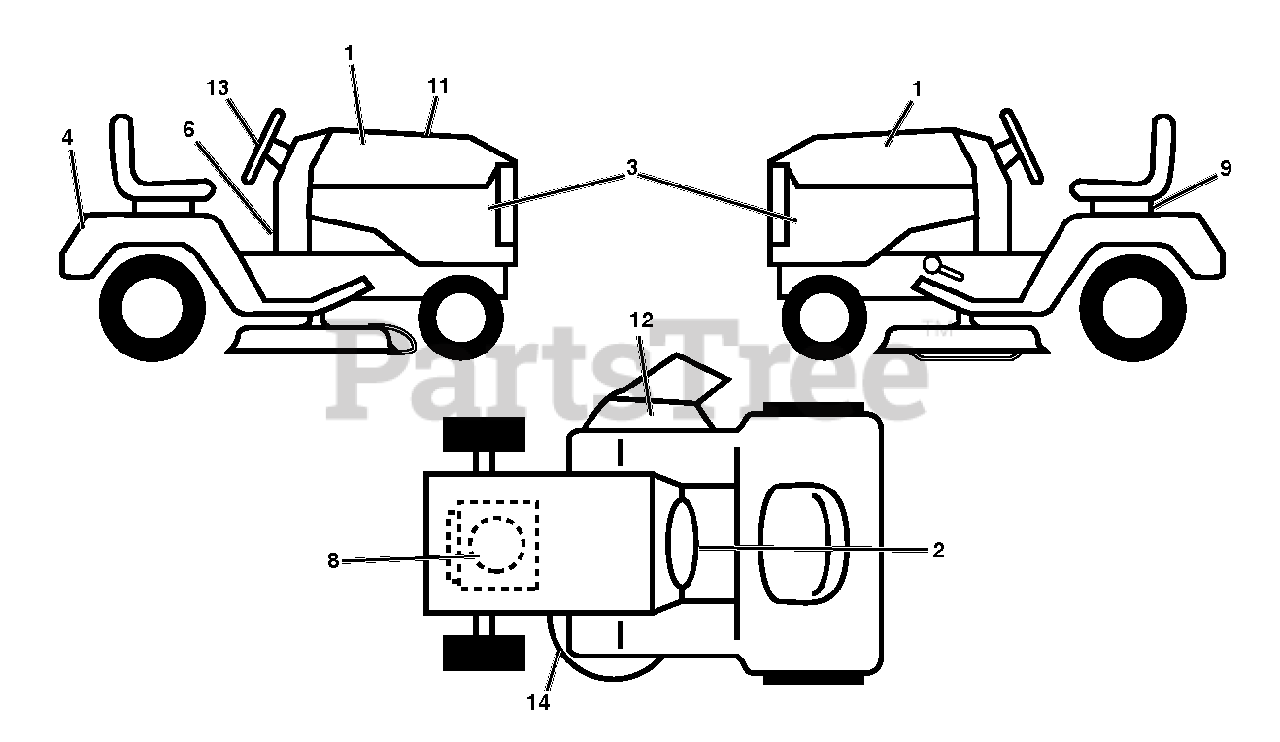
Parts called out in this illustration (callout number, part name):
1	DECAL.POULAN PRO.2015
2	DECAL.FENDER.WARNING.ENGLISH
3	DECAL TRACTOR SIDE PANEL DECAL
4	DECAL.REARFNDR.POULAN PRO.2015
6	DECAL, WARNING SPARK ARRESTOR
8	Decal, Engine BS 17_5PB DOM 381669
9	DECAL BTRY SYMBOLS
11	Decal, Replacement BSM31 PB TLW 3
12	DECAL, DECK DEFLECTOR, WARNING
13	Decal, Steering Wheel STDXXSQ PPRO 2015
14	DECAL.V-BELT.SCH.42/46"MEC/ELE
